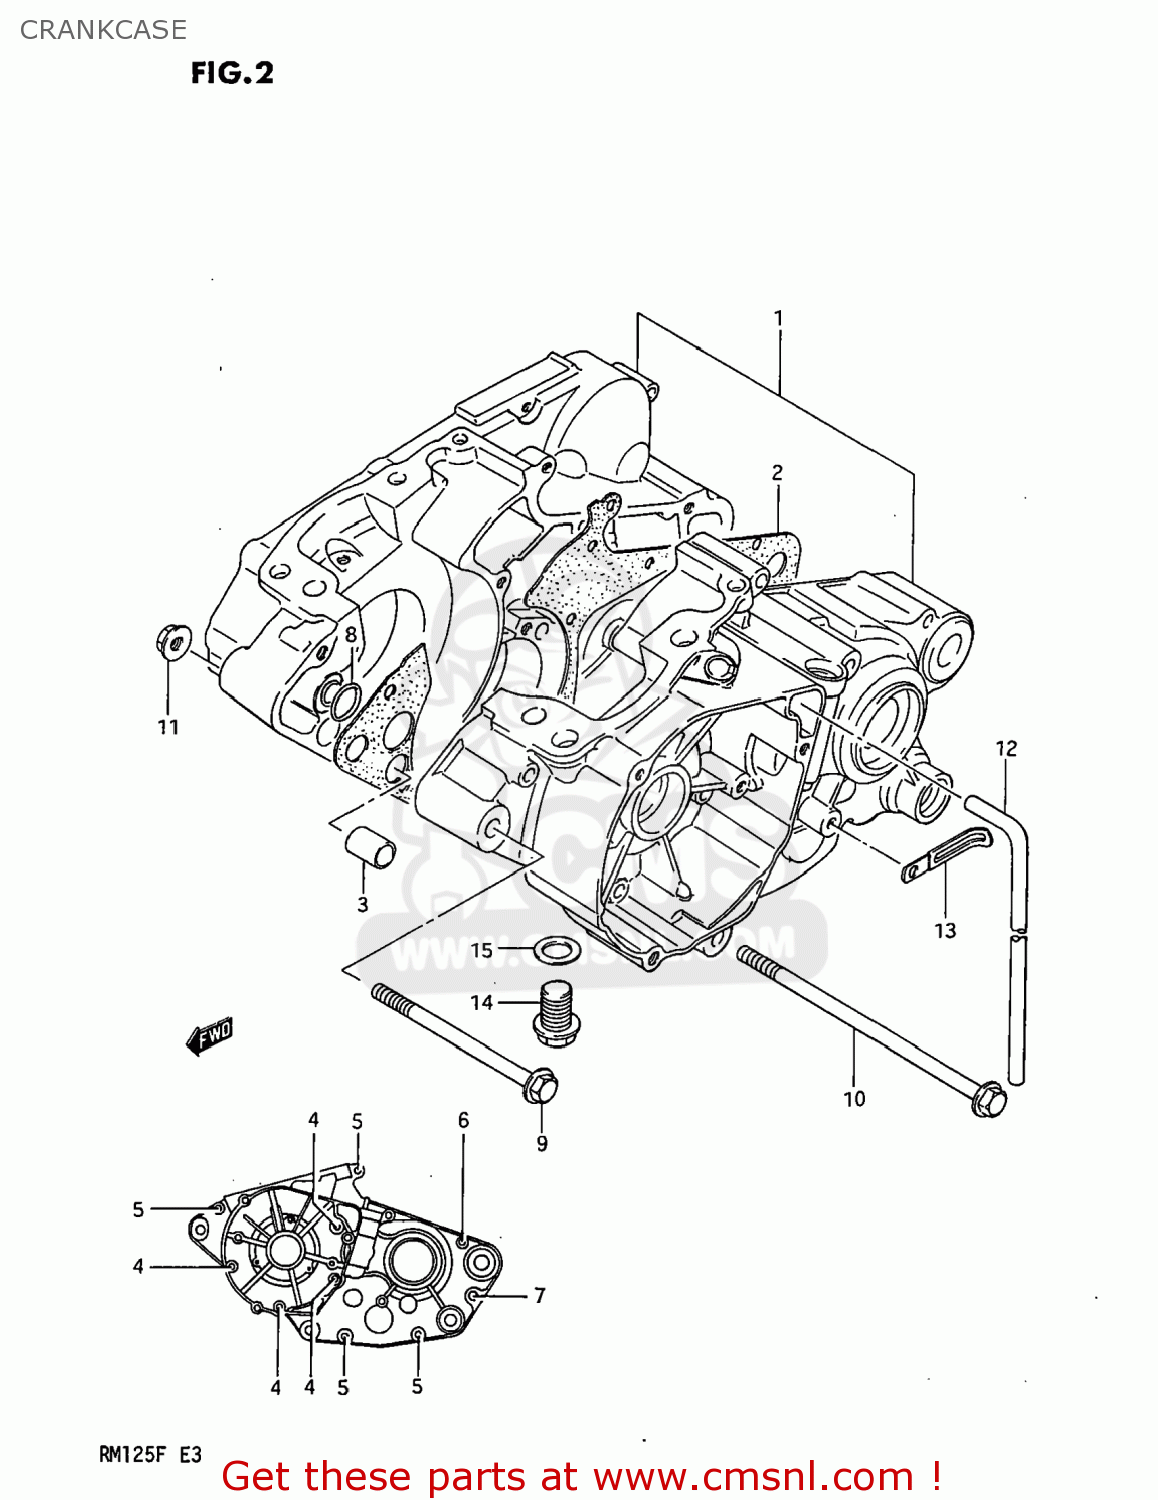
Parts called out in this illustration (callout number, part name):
1	CRANKCASE SET
2	GASKET,CRANKCASE (MCA)
3	PIN
4	SCREW
5	SCREW
6	SCREW
7	SCREW
8	O RING(D:1.9,ID:13.8)
9	BOLT(8X95)
10	BOLT(8X150)
11	NUT
12	HOSE
13	CLAMP
14	PLUG
15	GASKET(14X19.2X2) (NAS)
